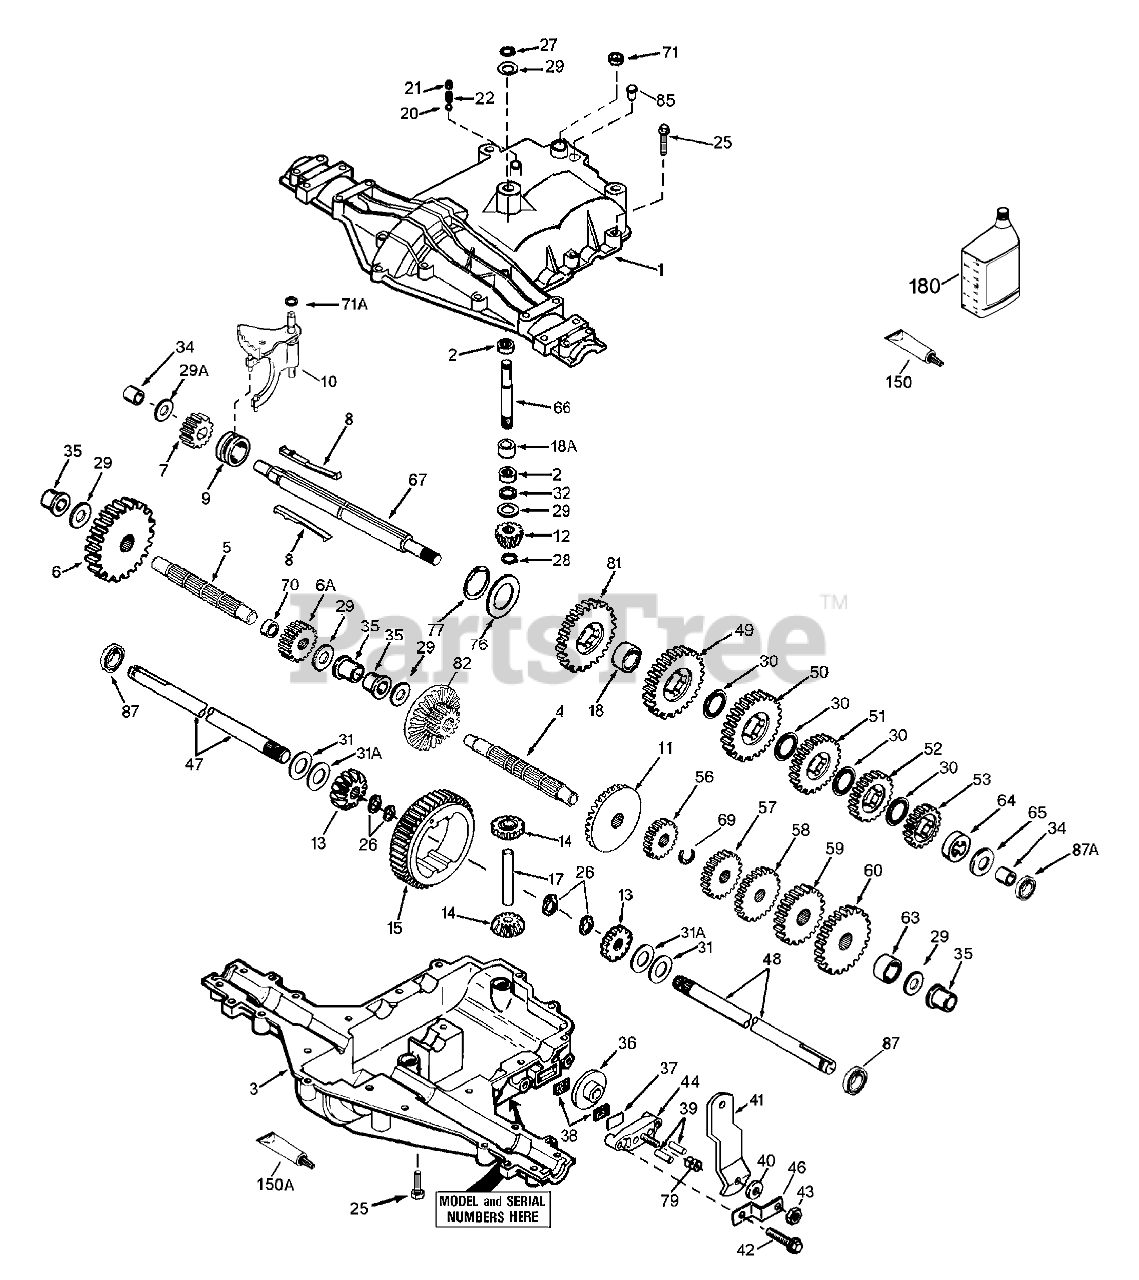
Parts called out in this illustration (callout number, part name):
1	Transaxle Cover
2	Bearing-Needle
3	Transaxle Case
4	Countershaft
5	Output Shaft
6	Spur Gear (38 teeth)
6A	Spur Gear (15 teeth-steel)
7	Spur Gear (11 teeth-steel)
8	Shift Key
9	Shift Collar
10	Shift Rod & Fork
11	Bevel Gear (30 teeth)
12	Input Bevel Pinion (13 teeth)
13	Bevel Gear (16 teeth-steel)(Incl. 14)
14	Bevel Gear (16 teeth-steel)(Incl. 13)
15	Ring Gear (43 teeth)
17	Drive Pin
18	Spacer
18A	Spacer
20	Ball-Steel
21	Screw-Set
22	Spring
25	Ring Set (.020 O S)
26	Retaining Ring (pkg of 2)
27	Ring-Snap
28	Ring-Retainer
29	Washer
29A	Washer
30	Washer
31	Washer
31A	Flat Washer (.062 wide)
32	Oil Seal
34	Bushing
35	Flanged Bushing
36	Brake Disk
37	Brake Pad Plate
38	Pad-Brake 2/Pkg
39	Dowel Pin
40	Washer
41	Brake Lever
42	Ring Set (.020 O S)
43	Locknut
44	Nozzle-Carburetor
46	Bracket
47	Axle (11-15/16" long)
48	Axle (16-1/2" long)
49	Spur Gear (29 teeth-steel)
50	Spur Gear (23 teeth-steel)
51	Spur Gear (20 teeth)
52	Spur Gear (16 teeth-steel)
53	Spur Gear (15 teeth-steel)
56	Spur Gear (11 teeth-steel)
57	Spur Gear (17 teeth-steel)
58	Spur Gear (20 teeth)
59	Spur Gear (24 teeth-steel)
60	Spur Gear (25 teeth)
63	Spacer
64	Spacer
65	Washer
66	Input Shaft
67	Shifter & Brake Shaft
69	Retaining Ring
70	Spacer
71	Cut Seal-Square
71A	"O" Ring
76	Washer
77	Inverted Retaining Ring
79	Piston ASM (.020 O S)
81	Spur Gear (27 Teeth)
82	Bevel & Spur Gear (30 & 13 teeth)
85	Pipe Plug
87	Oil Seal
87A	Oil Seal
150	Liquid Gasket RTV Silicone
150A	Liquid Gasket Loctite #242
180	Gear Oil
